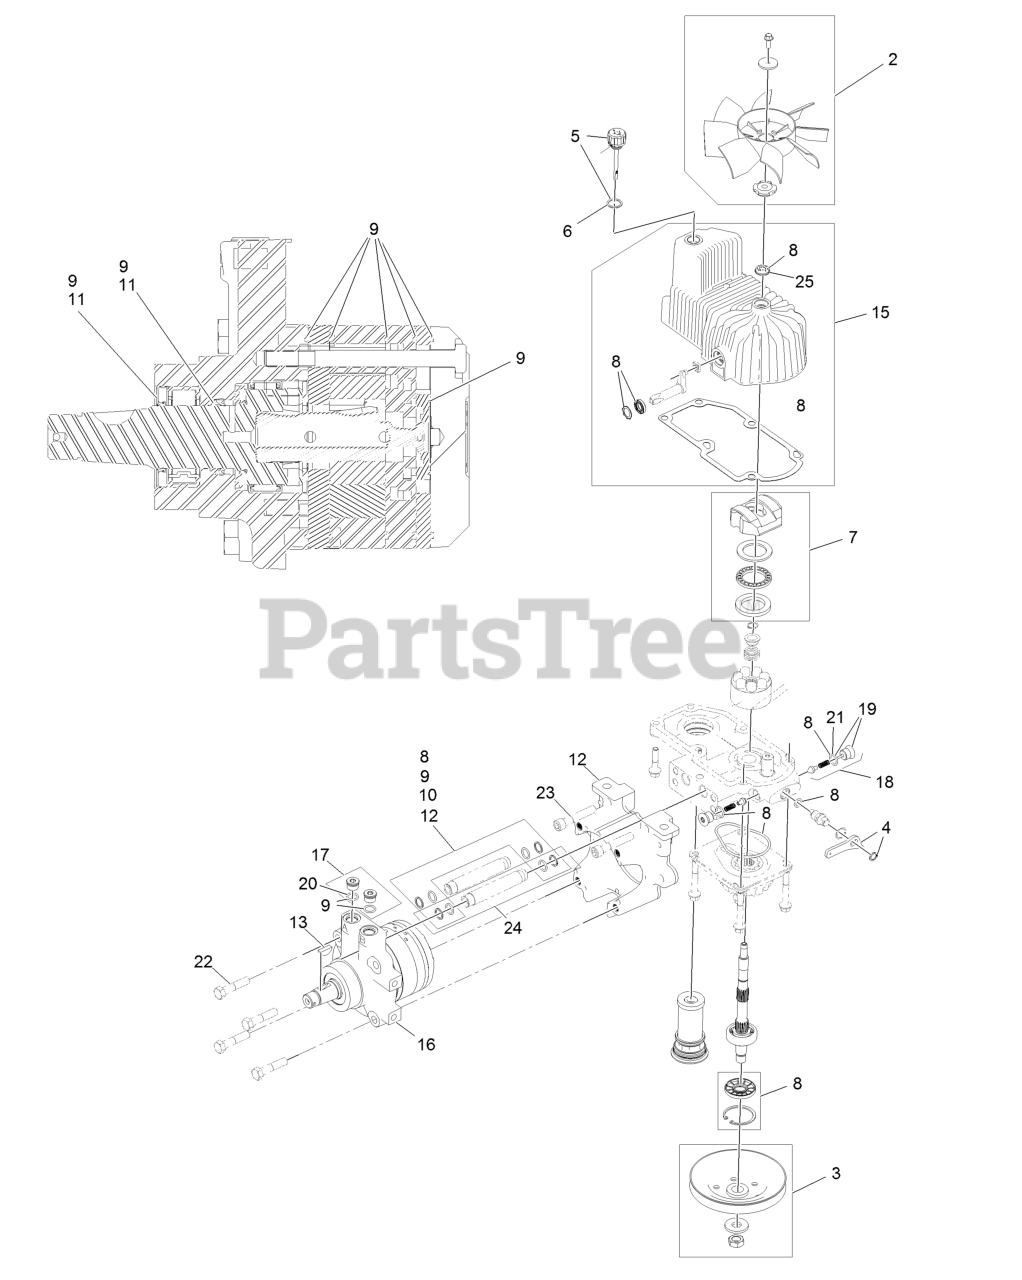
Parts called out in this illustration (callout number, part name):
2	FAN KIT
3	PULLEY KIT
4	HANDLE-BYPASS VALVE, HYDRO
5	DIPSTICK-HYDRO W/GASKET
6	GASKET-DIPSTICK, HYDRO
7	SWASH BLOCK KIT
8	PUMP SEAL KIT
9	MOTOR SEAL KIT
10	TUBE SEAL KIT
11	OUTPUT SHAFT SEAL KIT
12	NOSE CUP-UHT
13	KEY-WOODRUFF
15	HOUSING-HYDRO, LH
16	MOTOR-HYDRAULIC LH 240CC
17	MAGNETIC PLUGS SERVICE KIT
18	CHECK VALVE ASM
19	PLUG-CHECK (W/O-RING)
21	O-RING-CHECK VALVE
22	SCREW HH
23	SCREW-HSH
24	HYDRAULIC TUBE KIT
25	SEAL-FAN DRIVE
